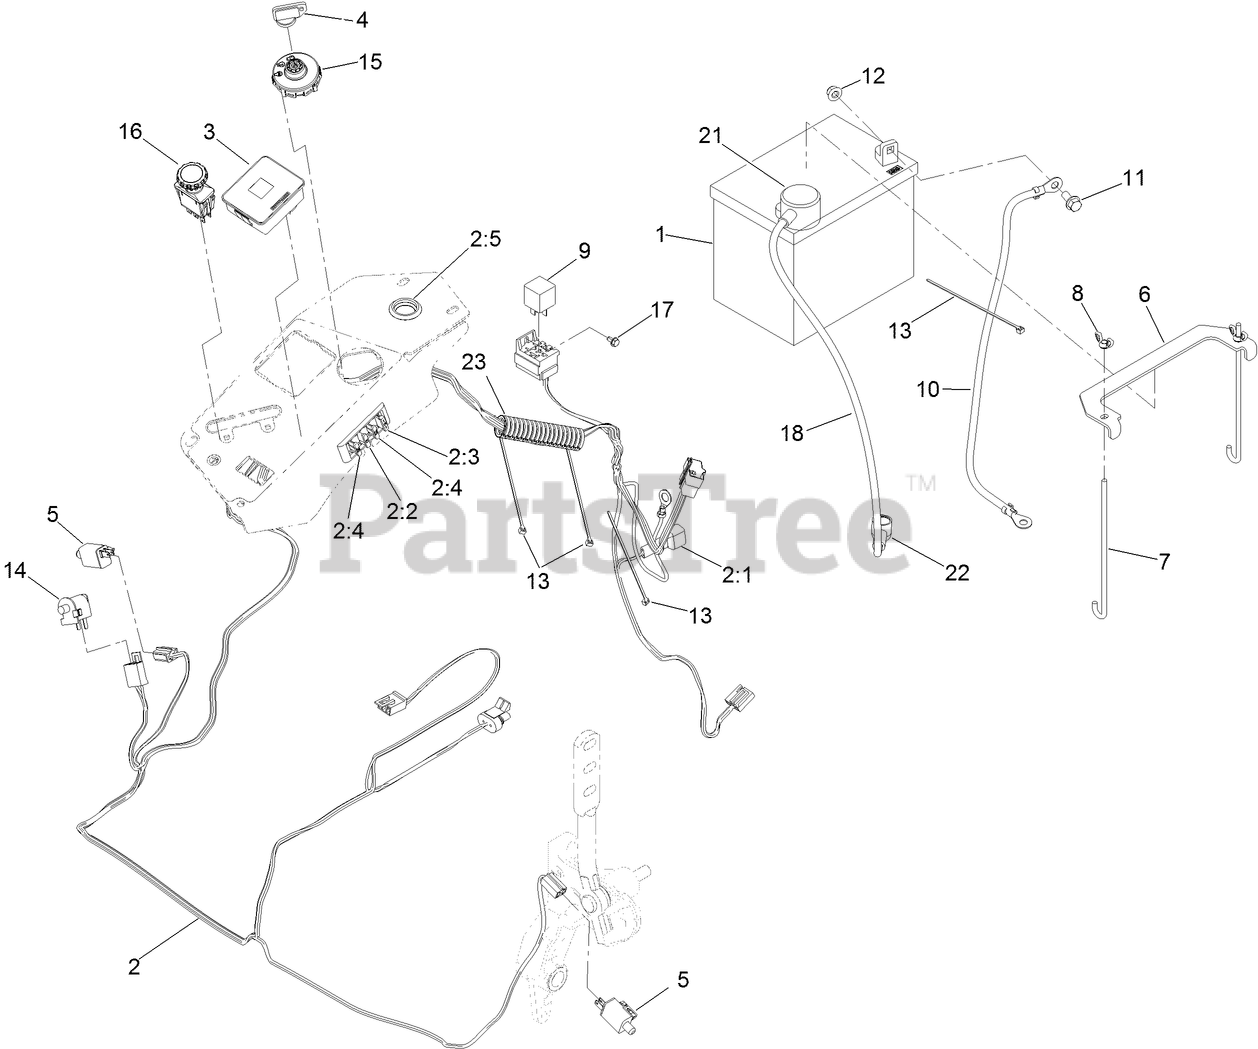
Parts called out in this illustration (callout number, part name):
1	BATTERY-DRY
2	HARNESS-WIRE, MAIN
2:2	FUSE-BLADE, 10 AMP
2:3	FUSE-BLADE, 15 AMP
2:4	FUSE-BLADE, 25 AMP
2:5	CAP-PLUG
3	FUEL/HOUR METER ASM
4	KEYS-IGNITION (SPARE PAIR)
4	KEY-IGNITION
5	SWITCH
6	STRAP-TIE DOWN, BATTERY
7	BOLT-HOLDDOWN
8	WINGNUT
10	CABLE-BATTERY, NEGATIVE
11	SCREW-HH
12	NUT-HF, NI
13	TIE-CABLE
14	SWITCH-BAIL
15	SWITCH-IGNITION
16	SWITCH-PTO, 10 AMP
17	SCREW-HWH
18	CABLE-BATTERY, POSITIVE
21	INSULATOR-BATTERY
22	INSULATOR-SOLENOID
23	COVER-HOSE
